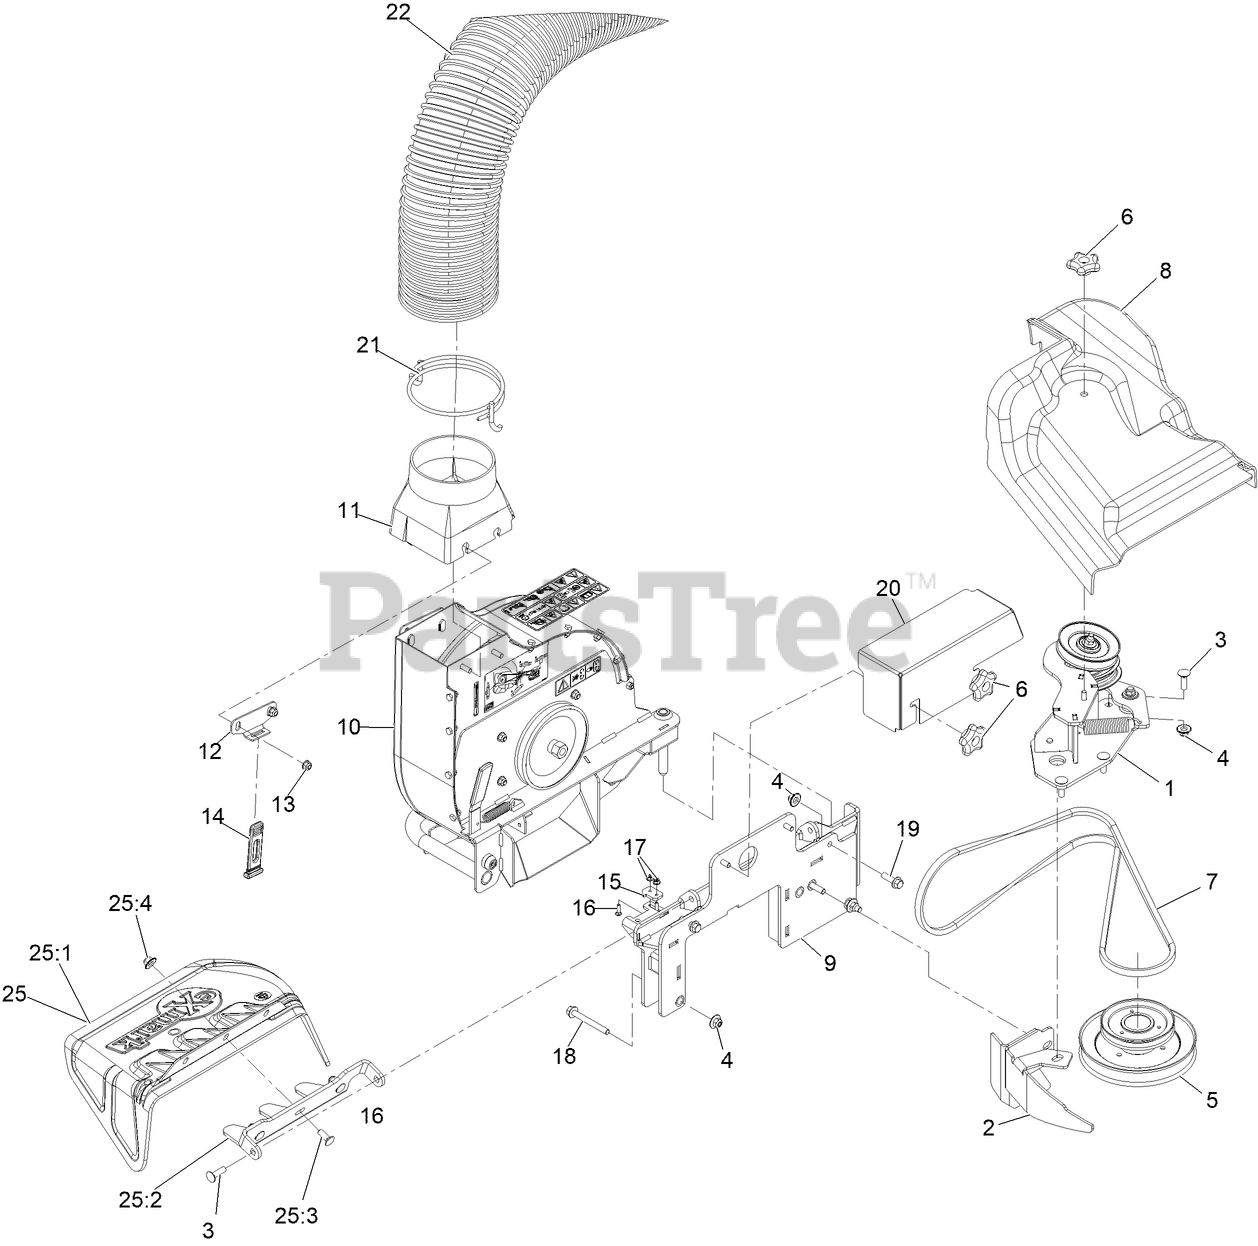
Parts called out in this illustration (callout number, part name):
1	ASM-Blower Idler
2	BAFFLE-DOGLEG
3	BOLT-CARR
4	Nut-Nyloc 3/8-16 Flg
5	JACKSHAFT,UV DRIVE 604 SPLINED
6	KNOB-HANDLE
8	Cover-Belt
9	MOUNT ASM-BLOWER
10	BLOWER ASM
11	TRANSITION
13	NUT-HF, NI
14	STRAP-DOWN, HOLD
15	PLATE-LATCH
16	SCREW-CARR
18	Screw-HHF
19	SCREW-HHF
20	Guard-Belt, Blower
21	CLAMP-HOSE, BAGGER
22	HOSE-FLEXIBLE
25	ASM,DISCHARGE CHUTE
25:1	CHUTE,DISCHARGE
25:2	BRACKET,DISCHARGE CHUTE
25:3	SCREW-CARR
25:4	Nut-Nyloc 3/8-16 Flg
